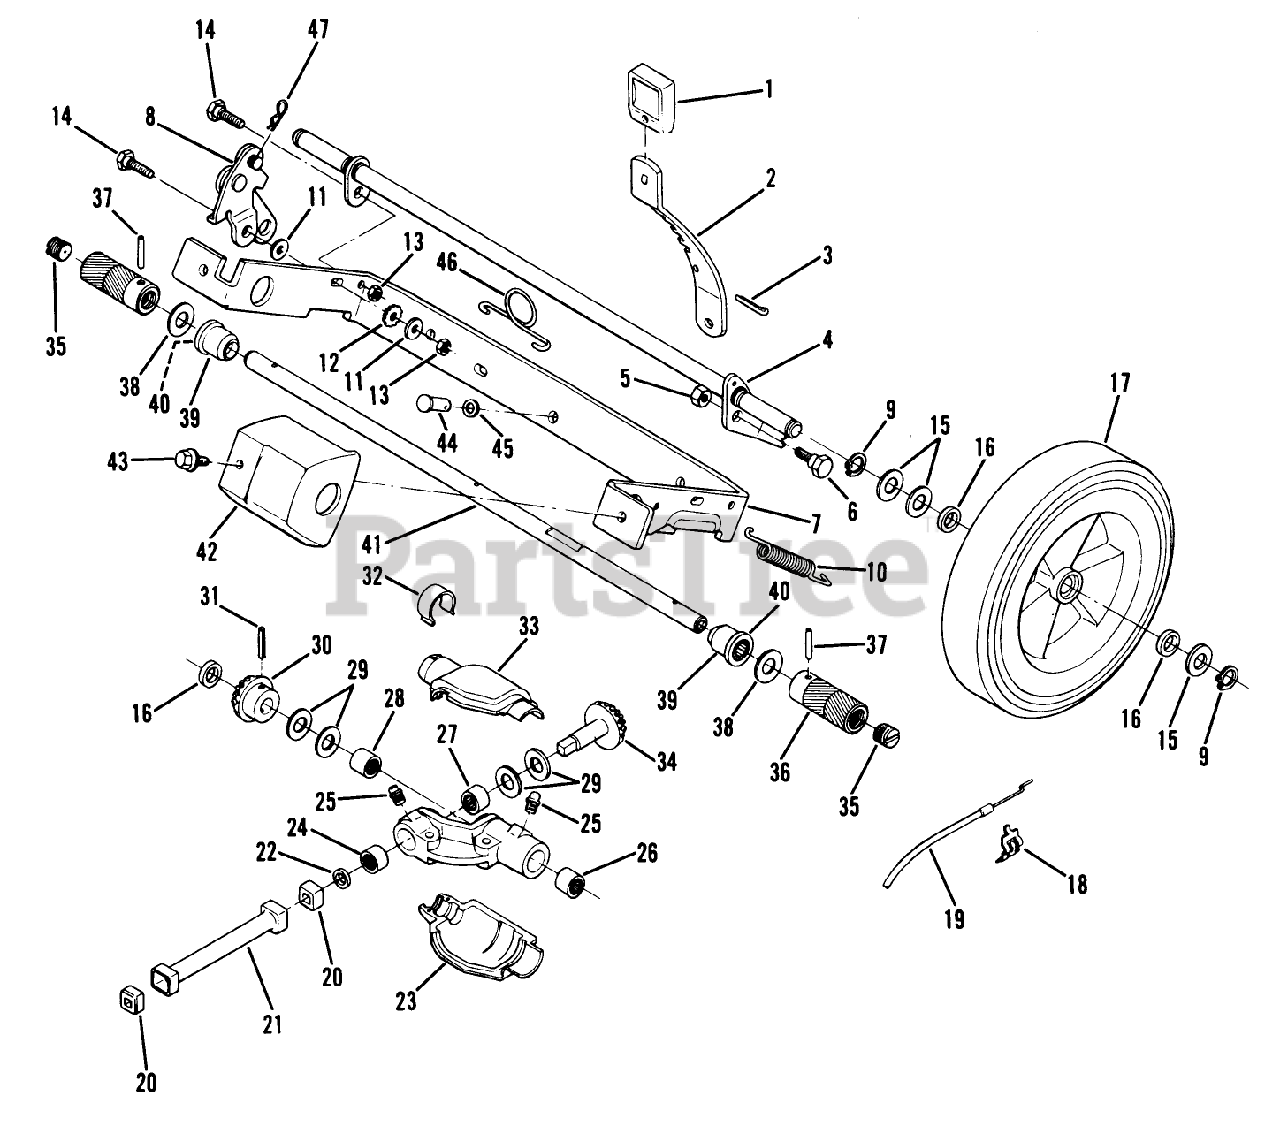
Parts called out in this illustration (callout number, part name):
1	KNOB
2	LEVER
5	LOCKNUT E
6	BOLT RB&W
9	RET RING
10	SPRING
11	WASHER S
13	STOP NUT
14	BOLT RB&W
15	SPACER
16	WASHER
20	BUSHING
22	O Ring
25	**FITTING LINCOLN
27	NEEDLE BEARING
29	THRUST WASHER
31	ROLL PIN
33	GEAR COVER UPPER
35	GREASE PLUG
37	PIN
40	BEARING AY F
41	DRIVE SHFT TAG AY
42	GUARD
44	PIN
45	WASHER SPRING LAR
46	SPRING N.A.S
